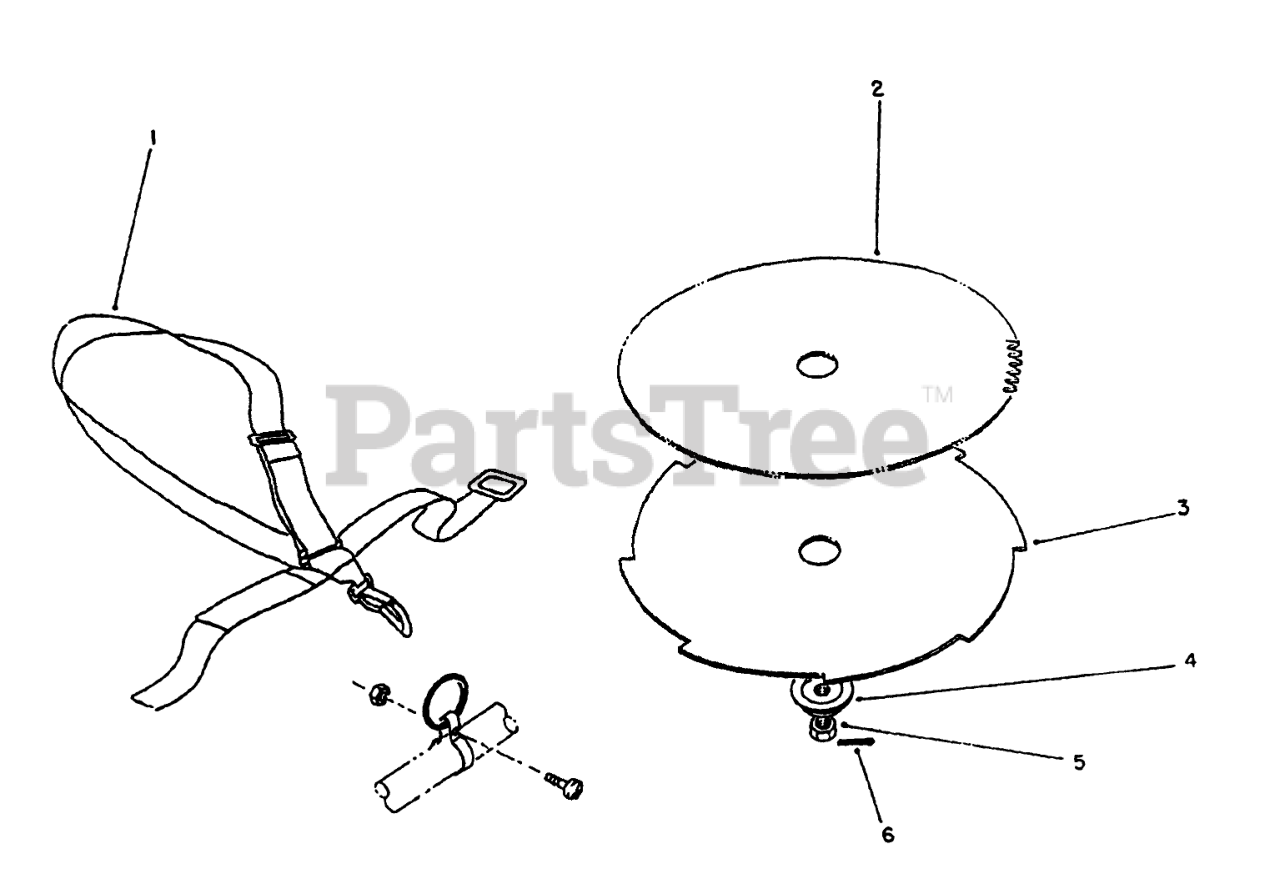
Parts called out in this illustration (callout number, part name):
1	Deluxe Harness
2	SAW BLD PKG(8", 80T)
3	BRUSH BLD PKG(8",8T)
4	Adapter-Blade
6	1/16 X 1 LG COTTER PIN
